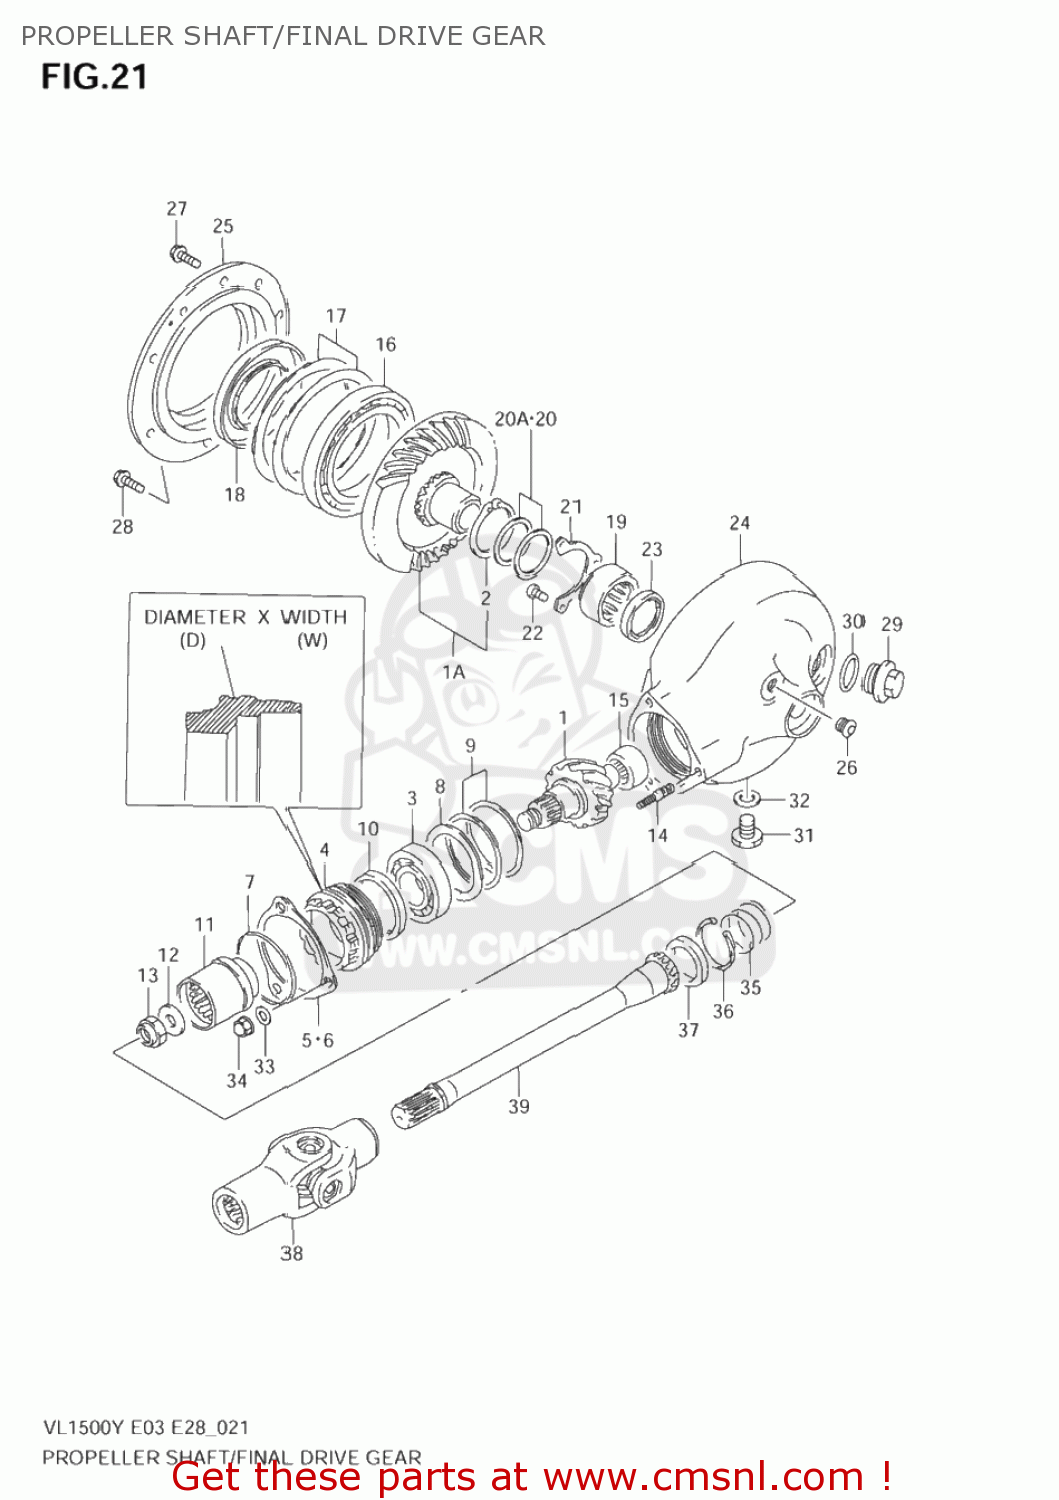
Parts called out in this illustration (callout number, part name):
1	GEAR,FINAL DRIVE BEVEL
1A	GEAR,FINAL DRIVEN BEVEL
2	.CIRCLIP
3	BEARING(28X68X18)
4	STOPPER,FINAL DRIVE BEARING
5	PLATE,BEARING STOPPER
6	PLATE,BEARING STOPPER
7	O RING(D:3.1,ID:63.9)
8	WASHER(54X68X1.5)
9	SHIM SET,FINAL DRIVE GEAR
10	SEAL,OIL
11	COUPLING,FINAL DRIVE GEAR
12	WASHER(16X29X4)
13	NUT
14	BOLT
15	BEARING(20X34X18)
16	BEARING(85X130X14)
17	SHIM SET,FINAL DRIVEN GEAR
18	SEAL,OIL(70X110X14.7)
19	BEARING(35X48X23.7)
20	WASHER(35X46X0.95)
20A	SHIM SET,FINAL DRIVEN GEAR
21	RETAINER,FINAL DRIVEN GEAR BRG
22	SCREW
23	SEAL,OIL(35X43X5)
24	CASE,FINAL GEAR
25	CASE,FINAL GEAR BEARING
26	PLUG
27	BOLT
28	BOLT
29	PLUG,30X9
30	O RING(D:3.1,ID:26.4)
31	PLUG
32	GASKET(13.8X18.8X4.8) (NAS)
33	WASHER
34	NUT
35	SPRING
36	CIRCLIP
37	SEAL,OIL(30X40.5X5.5)
38	YOKE COMP,UNIVERSAL JOINT
39	SHAFT,PROPELLER
